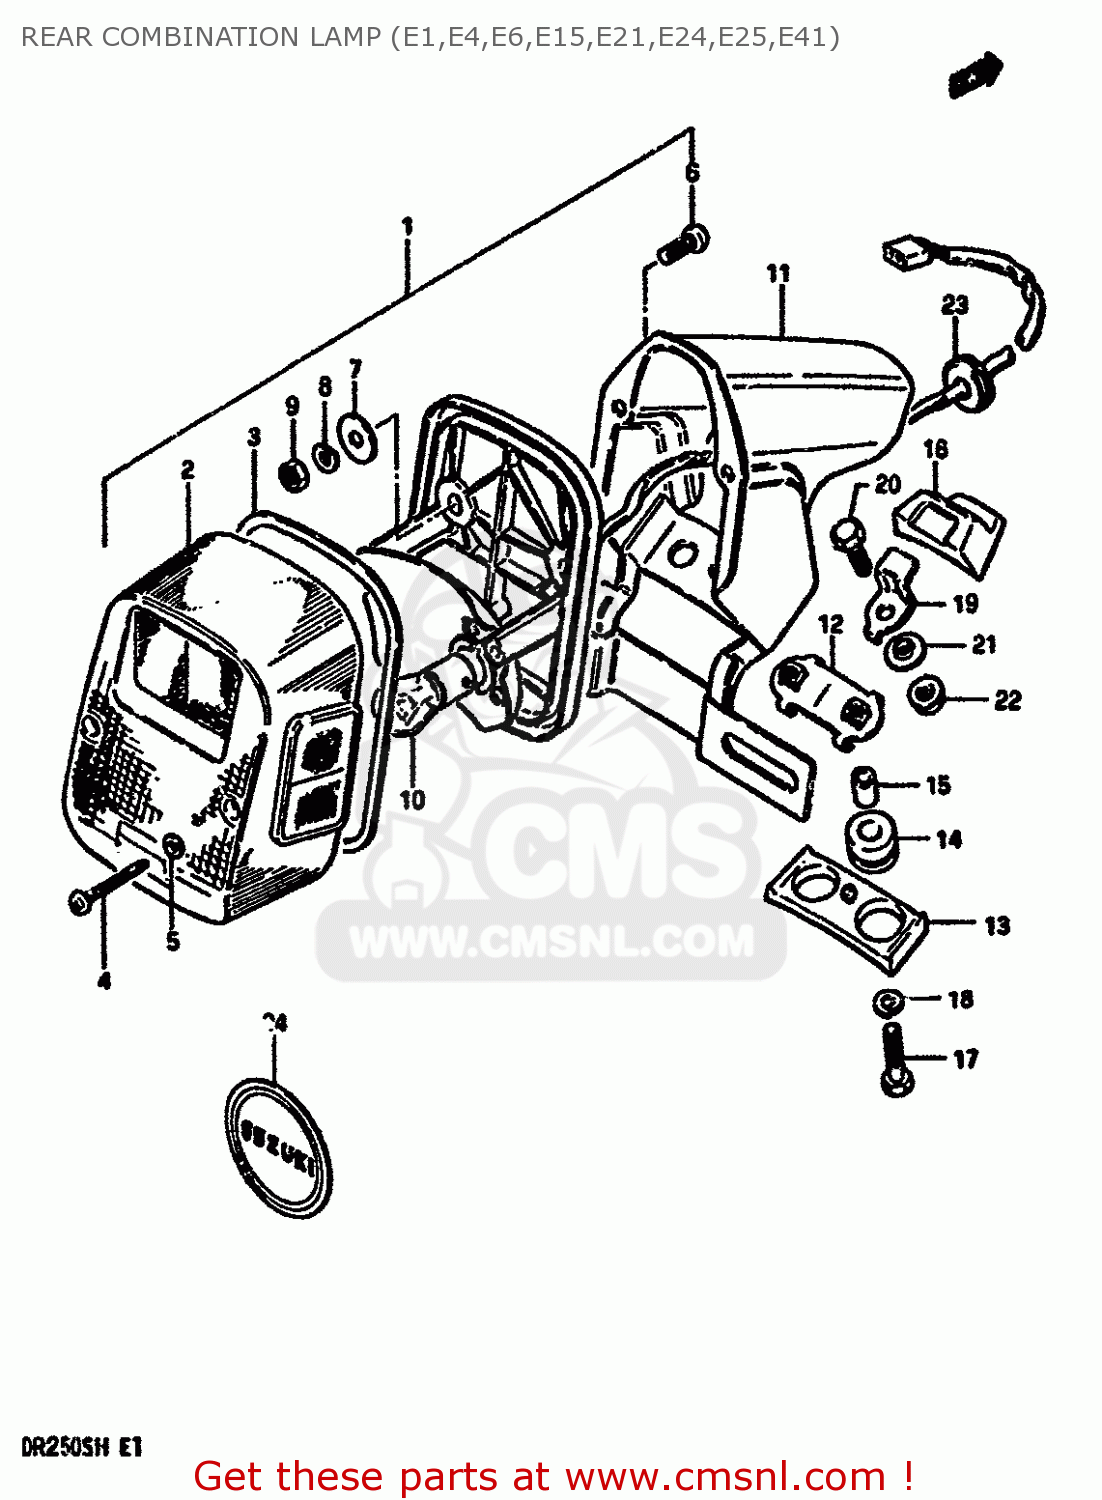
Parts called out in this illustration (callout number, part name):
1	LAMP UNIT,RR COMBNATION
2	LENS
3	GASKET (NAS)
4	SCREW
5	GASKET (NAS)
6	SCREW
7	WASHER,REAR COMBINATION LAMP
8	LOCK WASHER
9	NUT
10	BULB 12V21/5W
11	BRACKET UNIT,TAIL LAMP
12	PLATE
13	CUSHION
14	CUSHION
15	SPACER
16	CUSHION,REAR COMBINATION LAMP
17	BOLT
18	WASHER,LOCK
19	PLATE,RR COMBINATION LAMP
20	BOLT
21	WASHER,LOCK
22	NUT
23	GROMMET
24	EMBLEM, REAR
